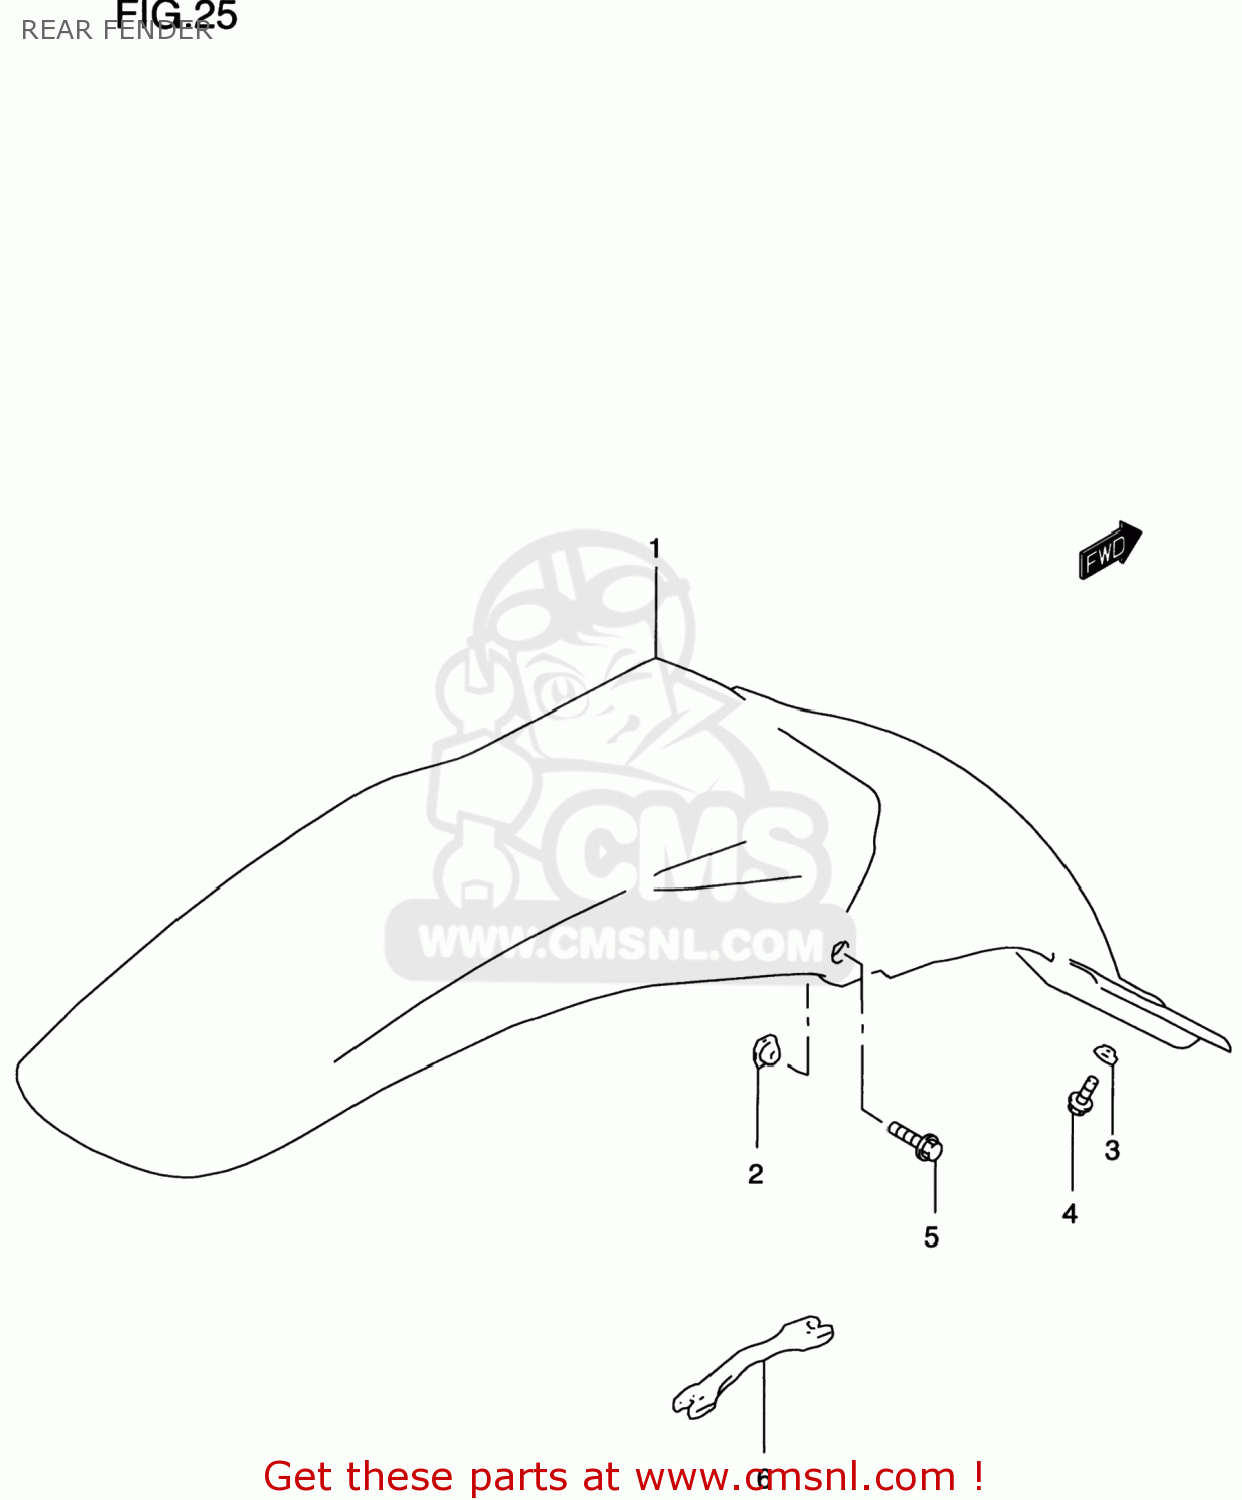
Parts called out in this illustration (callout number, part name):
1	FENDER,RR
2	NUT
3	WASHER
4	BOLT
5	BOLT
6	SPANNER,OPEN
